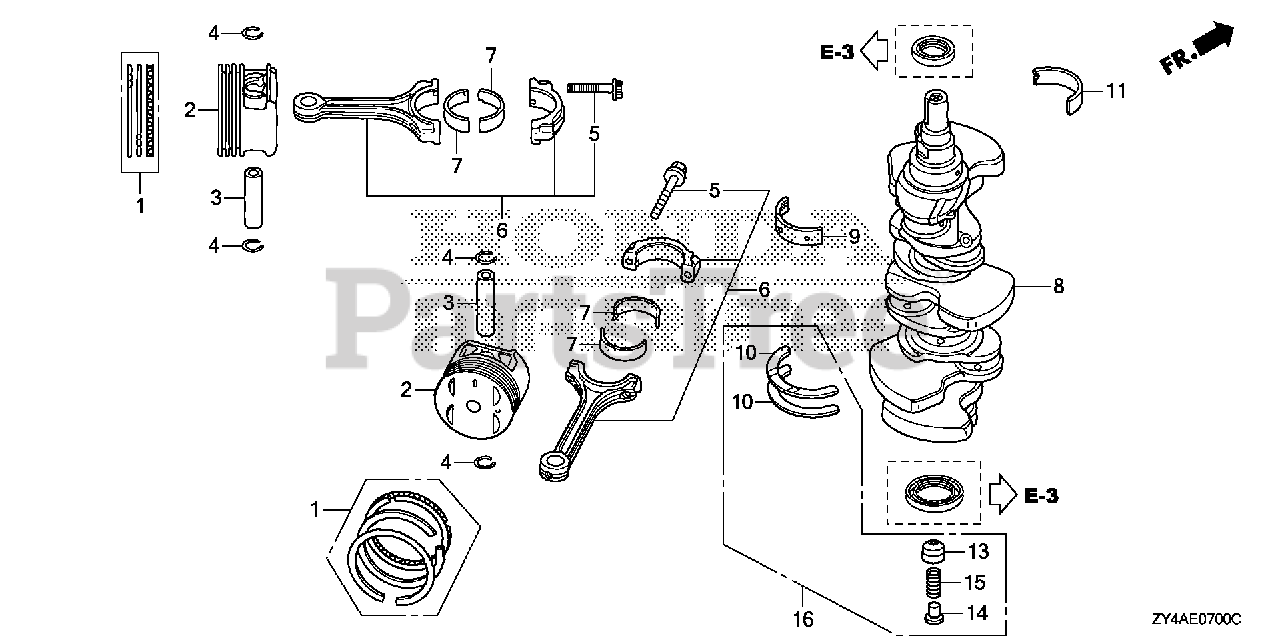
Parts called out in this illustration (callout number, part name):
1	RING SET, PISTON (STD)
1	RING SET, PISTON (0.25)
2	PISTON (0.25)
3	PIN, PISTON
4	CLIP, PISTON PIN
5	BOLT, CONNECTING ROD
6	ROD, CONNECTING
7	BEARING A, CONNECTING ROD (BLACK) (TAIHO)
7	BEARING B, CONNECTING ROD (BROWN) (TAIHO)
7	BEARING C, CONNECTING ROD (GREEN) (TAIHO)
7	BEARING D, CONNECTING ROD (YELLOW) (TAIHO)
7	BEARING E, CONNECTING ROD (PINK) (TAIHO)
8	CRANKSHAFT
9	BEARING A, MAIN (UPPER) (BLACK) (DAIDO)
9	BEARING B, MAIN (UPPER) (BROWN) (DAIDO)
9	BEARING C, MAIN (UPPER) (GREEN) (DAIDO)
9	BEARING D, MAIN (UPPER) (YELLOW) (DAIDO)
9	BEARING E, MAIN (UPPER) (PINK) (DAIDO)
9	BEARING F, MAIN (UPPER) (RED) (DAIDO)
11	BEARING A, MAIN (LOWER) (BLACK) (DAIDO)
11	BEARING B, MAIN (LOWER) (BROWN) (DAIDO)
11	BEARING C, MAIN (LOWER) (GREEN) (DAIDO)
11	BEARING D, MAIN (LOWER) (YELLOW) (DAIDO)
11	BEARING E, MAIN (LOWER) (PINK) (DAIDO)
11	BEARING F, MAIN (LOWER) (RED) (DAIDO)
16	WASHER KIT, THRUST (175/200/225)
